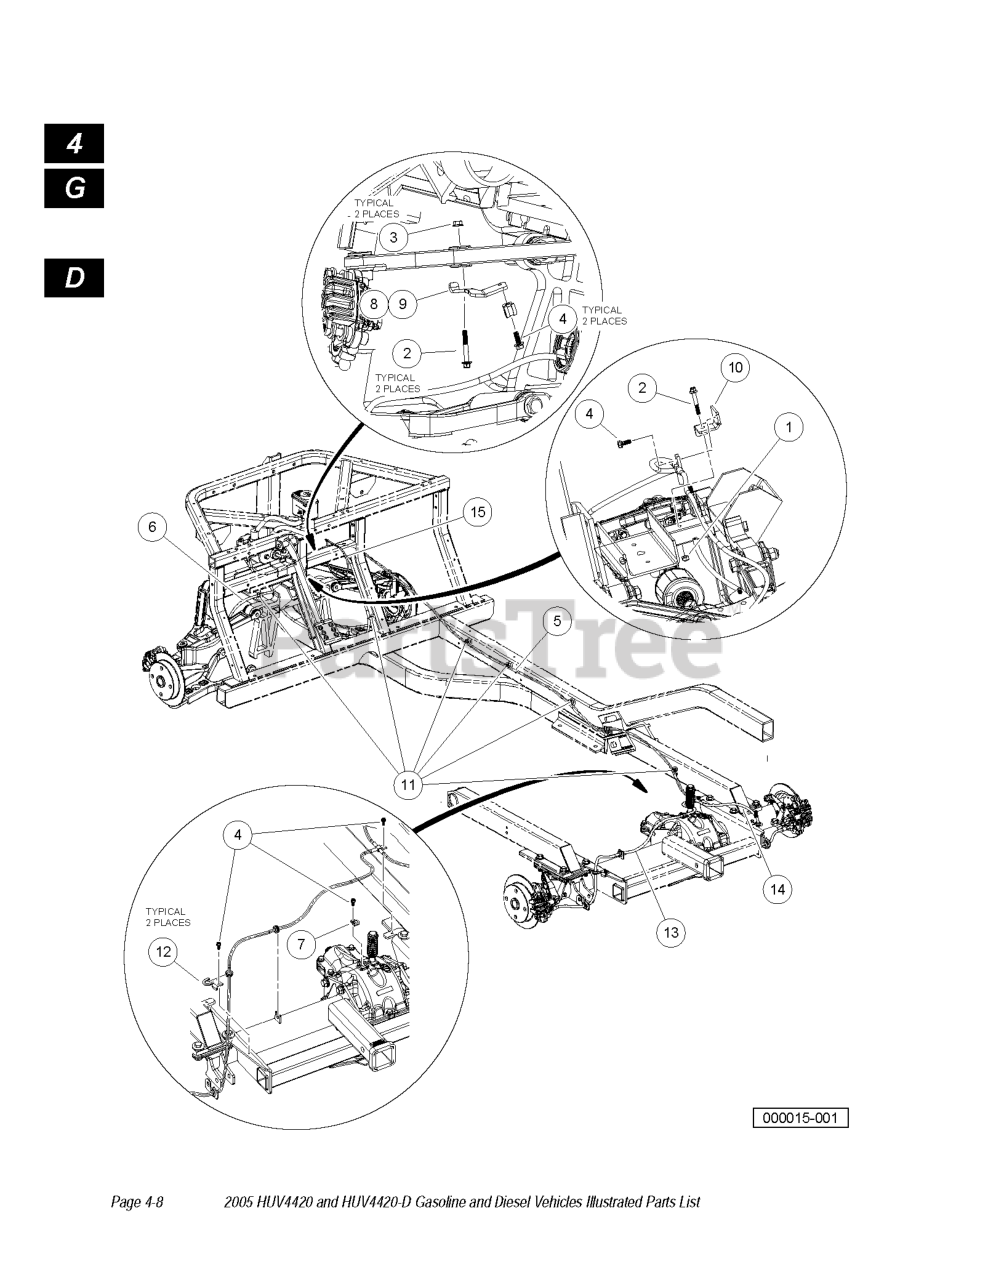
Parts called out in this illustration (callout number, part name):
1	LOCKNUT, M6-1.00 NYLON INSERT
2	BOLT - M6X1.0X40 HEX FLNG HD
3	NUT-M6X1.0 FLNG ALL MTL LOCK
4	SCREW, M6 X 16 TT HX FL HD
5	ASSEMBLY, BRAKE LINE, REAR
6	ASSEMBLY, BRAKELINE, FRONT
7	P-CLAMP, INSULATED .312 IN
8	BRACKET, BRAKELINE, LEFT
9	BRACKET, BRAKELINE, RIGHT
10	BRACKET, TEE, BRAKELINE
11	CLIP, BRAKE LINE
12	BRKT, LINE, HYD, RECVR
13	BRKT, LINE, HYD, SHK MNT, DRV
14	BRKT, LINE, HYD, SHK MNT, PASS
15	TIE WRAP , 11" NYLON
